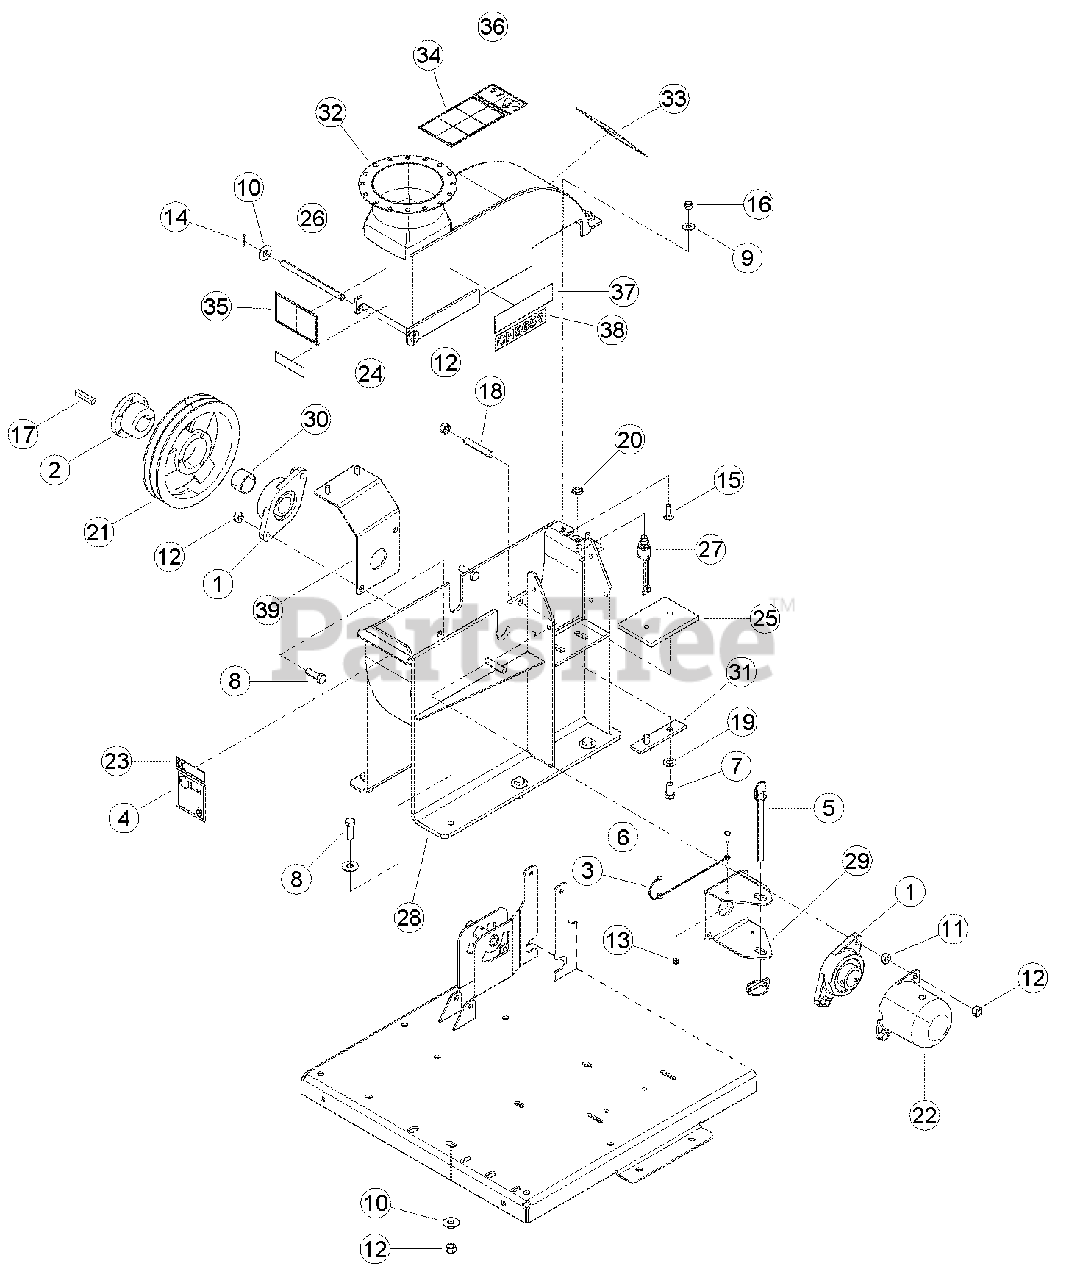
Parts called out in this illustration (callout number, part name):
1	BEARING, 1-1/2" 2-BOLT SET SCREW
2	BUSHING, SK 1-1/2"
3	LANYARD, NYLON
4	DECAL, 109 DB (CE COMPLIANT ONLY)
5	PIN, HITCH 1/2 X 6-1/2 W/LYNCH
6	BOLT, 1/4 X 3/4 HEX HD GR5 ZP
7	BOLT, 1/2 X 1 HEX HD GR5 ZP
8	BOLT, 1/2 X 1-1/4 HEX HD GR5 ZP
9	WASHER, 3/8 FLAT ZP
10	WASHER, 1/2 FLAT ZP
11	NUT, 1/2 HEX NC ZP
12	NUT, 1/2 CENTERLOCK GRB ZP
13	NUT, 1/4 NE NYLOCK ZP
14	PIN, 1/8 X 1.00 ZP COTTER
15	BOLT, 3/8 X 1-1/4 CRG GR5 NC ZP
16	NUT, 3/8 NE NYLOCK ZP
17	KEY, 3/8 SQUARE X 2 LONG PLAIN
18	STUD, 1/2-13 X 3 LONG B7 ZP
19	WASHER, 1/2 HI-STRENGTH SAE ZP
20	NUT, 5/8-32 JAM
21	SHEAVE, 2B 9.4 SK
22	CAP, LARGE SHAFT
23	DECAL, CH5653 INFORMATION (CE COMPLIANT ONLY)
24	DECAL, ATLANTIC BRIDGE LTD INFO (CE COMPLIANT ONLY)
25	ANVIL, 4 INCH CHIPPER
26	SHAFT, CHIPPER TOP PIVOT
27	ASSEMBLY, SEALED SWITCH
28	WELDMENT, CHIPPER BOTTOM
29	BRACKET, ROTOR LOCK
30	TUBE, 1.75 OD X .109 WALL X 1.250
31	STRIP, ADJUSTOR BLOCK
32	ASSEMBLY, CHIPPER TOP W/DECALS, SERVICE PART
33	DECAL, KNIFE ACCESS ISO
34	DECAL, OPERATING INSTRUCTIONS ISO
35	DECAL, DISCHARGE ISO
36	DECAL, MAINTENANCE ISO
37	DECAL, ECHO BEARCAT 6.82 X 1.90
38	DECAL, MODEL CH5653
39	BELT GUARD SUPPORT (REPLACED AND SUPERSEDED. FOR SERVICE ORDER PN 77249-12, BELT GUARD SUPPORT)
39	WELDMENT, BELT GUARD SUPPORT
